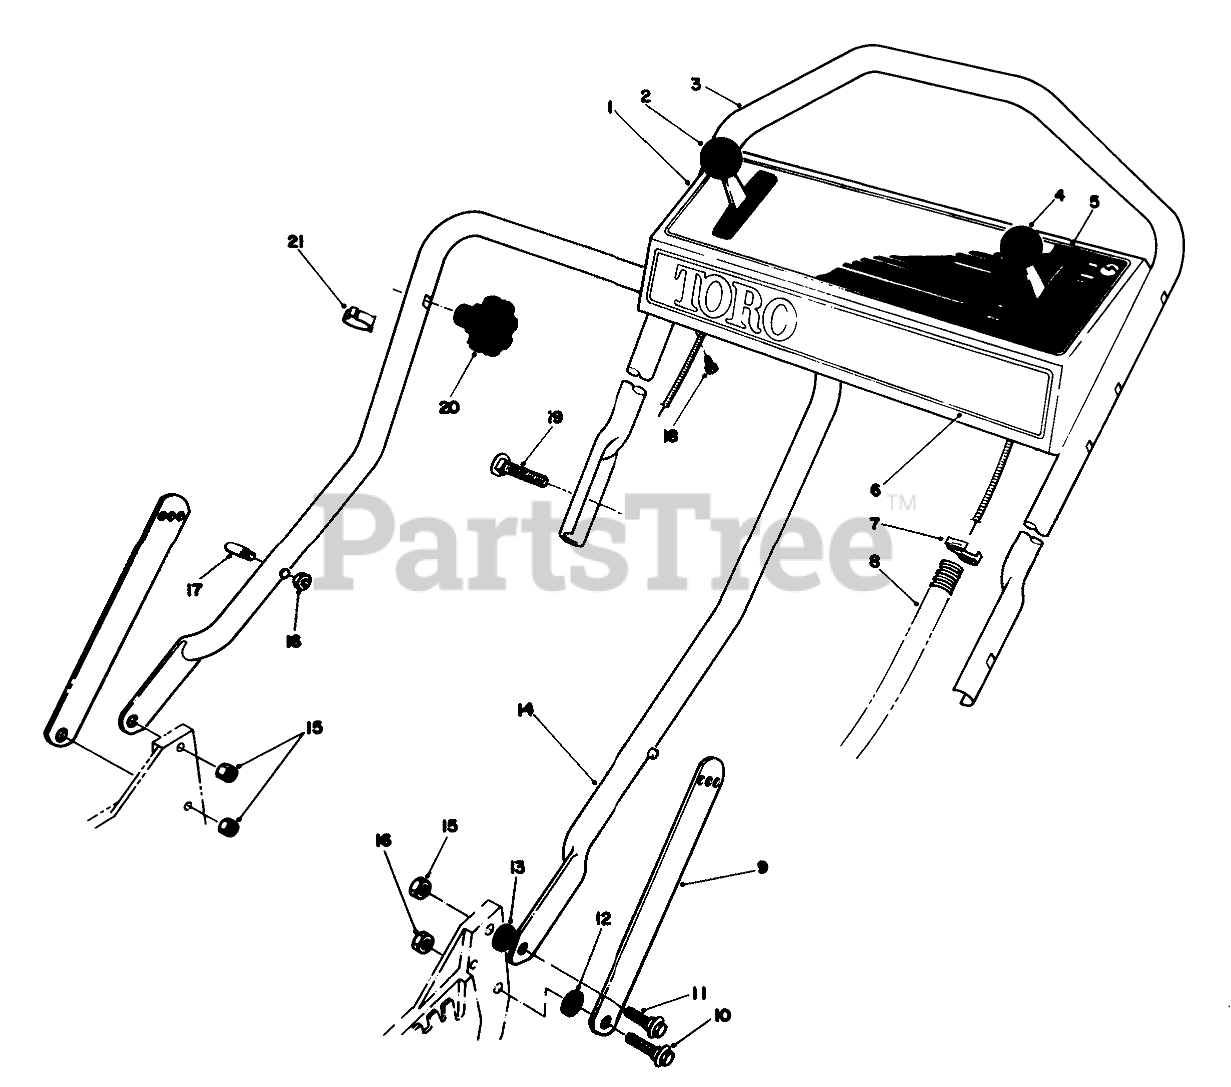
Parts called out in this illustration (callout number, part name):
1	Panel-Control (Incl. Ref. #5)
2	GROUND SPEED CONTROL
3	Handle-Upper
4	THROTTLE CONT-SERVICE
5	Decal-Instruction Panel
6	Decal-Toro
7	FITTING-RING
8	CONTROL CABLE COVER
9	Handle Latch
10	SCREW-SHOULDER
11	SCREW-SHOULDER
12	SPACER
13	SPACER
14	LOWER HANDLE ASM
15	NUT-LOCK, NI
16	NUT-LOCK, NI
17	HANDLE PIN
18	SCREW-HWHTF
19	5/16-18 X 2 HNDLE SCREW
21	BOWDEN CLIP
